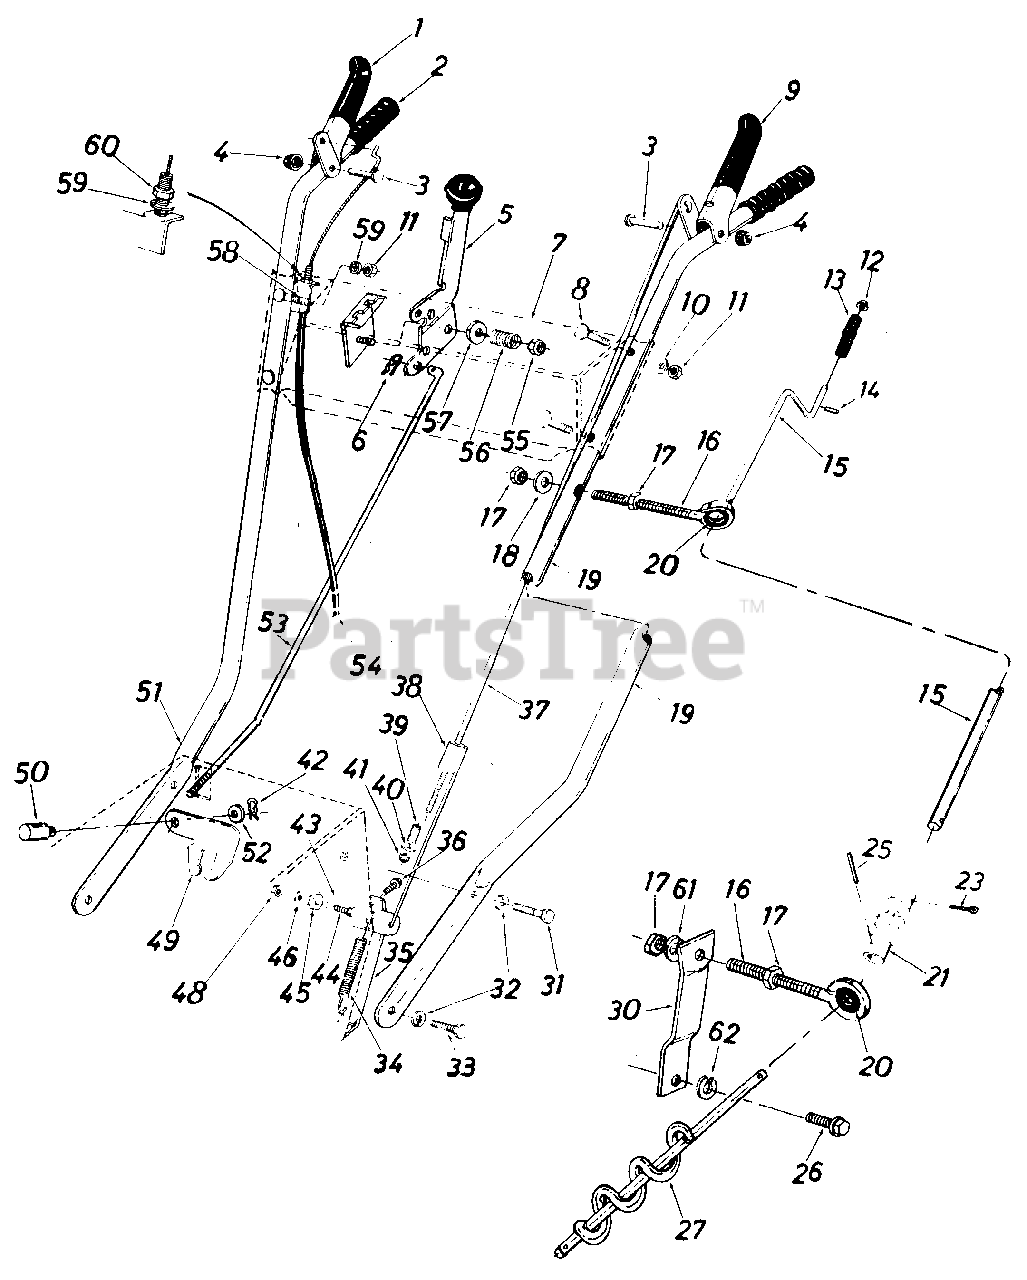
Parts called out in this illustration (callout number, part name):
1	Drive Clutch Grip Ass'y.
3	Clevis Pin .375" Dia.
4	Push Cap .375" Rod-Black
5	Shifting Handle Ass'y.
6	Int. Coter Pin 5/16" Dia.
7	Handle Panel Ass'y.
8	Carriage Bolt 5/16-18 x 1.75 Lg.
9	Auger Clutch Grip Ass y.
10	Bell-Wash. .345" I.D. x .88" O.D.
11	Hex Nut 5/16-18 Thd.
12	Push Nut 3/8" Rod
13	Black Knob
14	Roll Pin 1/8" Dia.
15	Chute Crank .375" Dia. x 34.5" Lg.
16	Eye Bolt 5/16-18 x 3.0" Lg.
17	Hex Nut 5/16-18 Thd.
18	Bell-Wash. .34" I.D. x .88" O.D.
19	Handle-L.H.
20	Grommet
21	Joint Brkt. Ass'y.
23	Coter Pin 3/32" Dia. x 1.00"
25	Spring Pin Roll 3/32" Dia. x .50" Lg.
26	Hex Self-Tap Scr. 3/8-16 x .75" Lg.
27	Chute Crank Ass'y.R.H. 10" Lg.
30	Chute Crank Supt. Plate 1.25" x 4.12" Lg.
31	Hex Self-Tap Scr. 3/8-16 x .75" Lg.
32	Bell-Wash. .44" I.D. x .88 O.D.
33	Hex Self-Tap Scr. 3/8-16 x .75" Lg.
34	Extension Spring .38" O.D. x 3.25" Lg.
35	Frame Cover
36	Hex Self-Tap Scr. 1/4-20 x .50" Lg.
37	Clutch Rod .214" Dia. x 32.0" Lg.
38	Auger Clutch Rod Ass'y.
39	Compression Spring .39" O.D. x .75" Lg.
40	Fl-Wash. .28" I.D. x .751" O.D.
41	Hex Ins. L-Nut 1/4-20 Thd.
42	Coter Pin 3132" Dia. x .75 Lg.
43	Clutch Bracket
44	Hex Sems Bolt 5/16-18 x 1.0" Lg.
45	Shoulder Spacer
46	Fl-Wash. .34" I.D. x 1.12" O.D.
48	Hex L-Nut 5/16-18 Thd.
49	Shifting Bracket
50	Ferrule
51	Handle-R.H.
52	Fl-Wash. .344" I.D. x .62" O.D.
53	Shifting Rod
54	Drive Clutch Control Cable
55	Hex Ins. Jam L-Nut 3/8-24 Thd.
56	Compression Spring .60" O.D. x .88" Lg.
57	Bell-Wash. .40" I.D. x .88" O.D.
58	Cable Support Brkt.
59	L-Wash. 5/16" I.D.
60	Hex Jam Nut 5/16-24 Thd.
61	Bell-Wash. .345" I.D. x .88" O.D.
62	L-Wash. 3/8" I.D.
